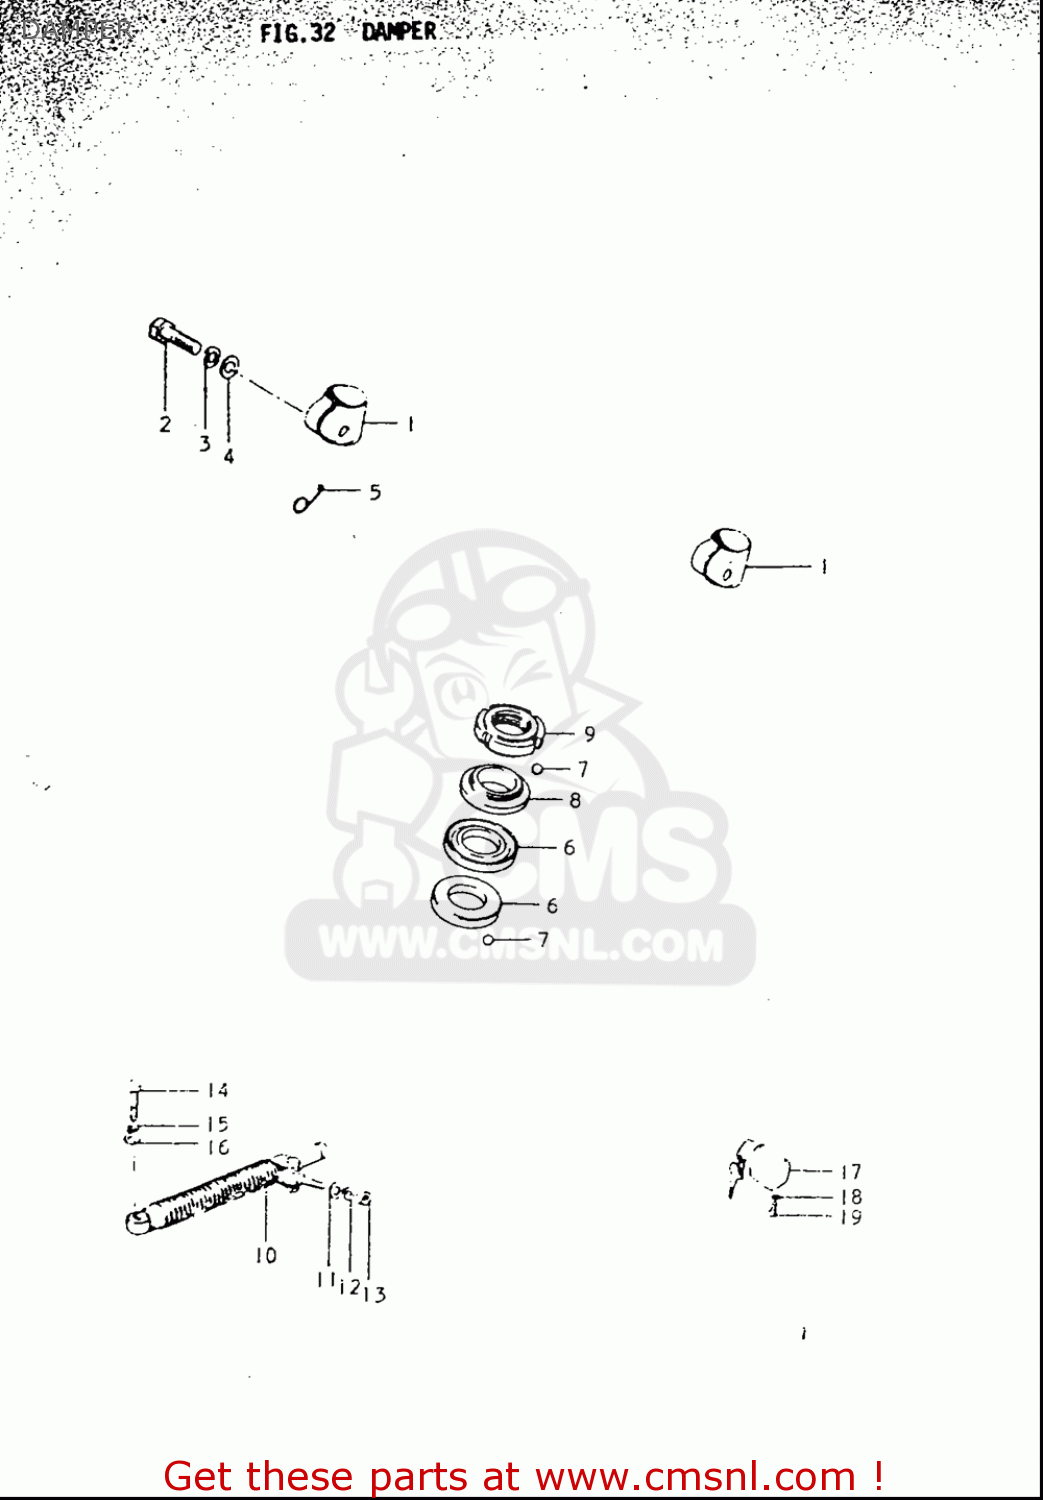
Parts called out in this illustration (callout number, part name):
3	WASHER,LOCK
4	WASHER
5	CLIP
7	BALL
9	NUT,STEERING STEM
11	WASHER
12	WASHER,LOCK
13	NUT
14	BOLT
15	WASHER,LOCK
16	WASHER
18	WASHER,LOCK
19	SCREW
